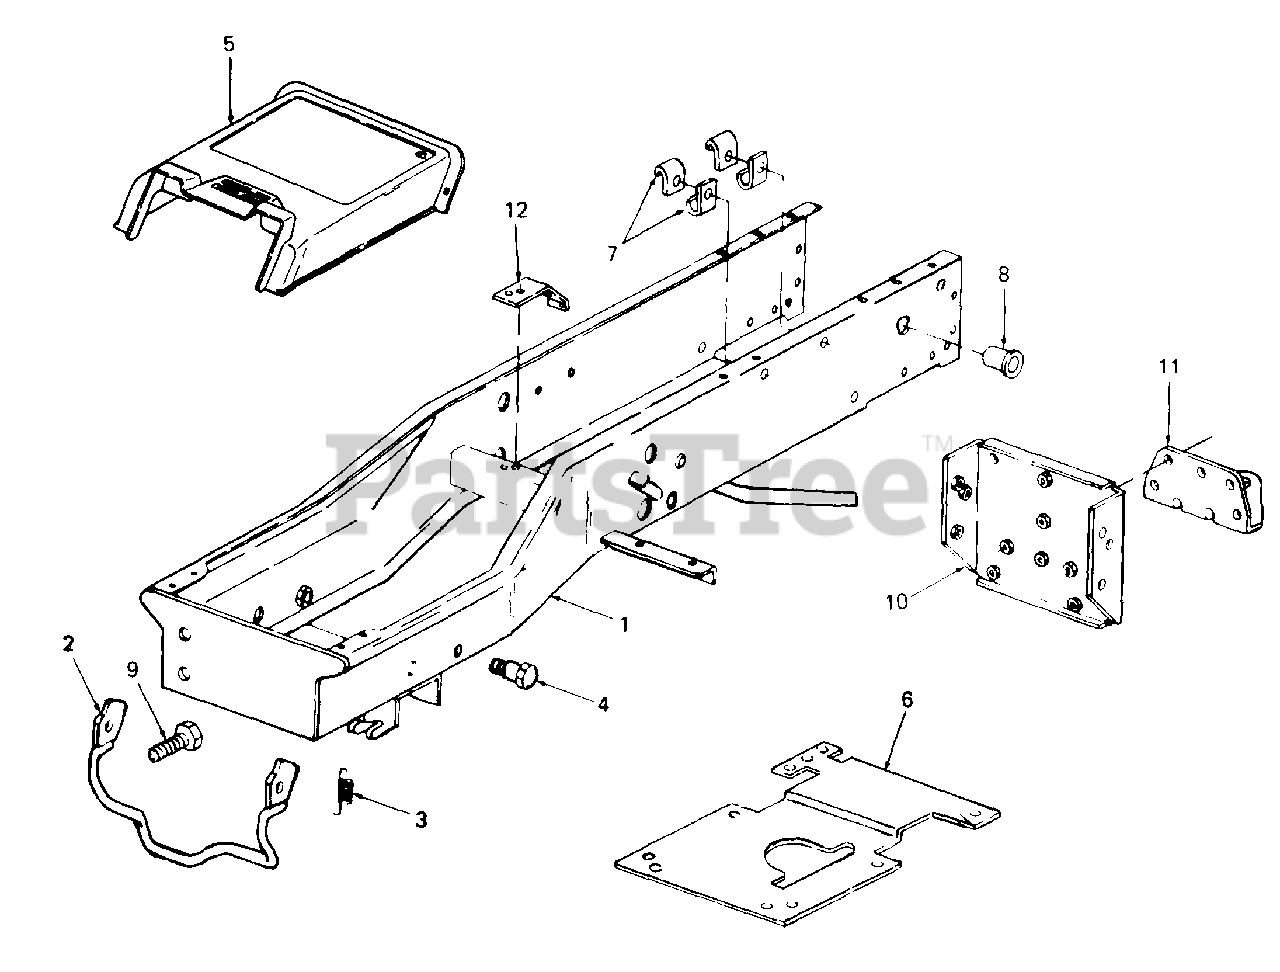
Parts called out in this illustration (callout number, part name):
3	Spring, Latch
4	Bolt, Shoulder
5	Cover, Frame
7	Clip, Cable
8	Bushing, Snap
9	Screw, Adjustment, 1/2-20 X 1.0 Lg GR5
12	Bracket, Switch
